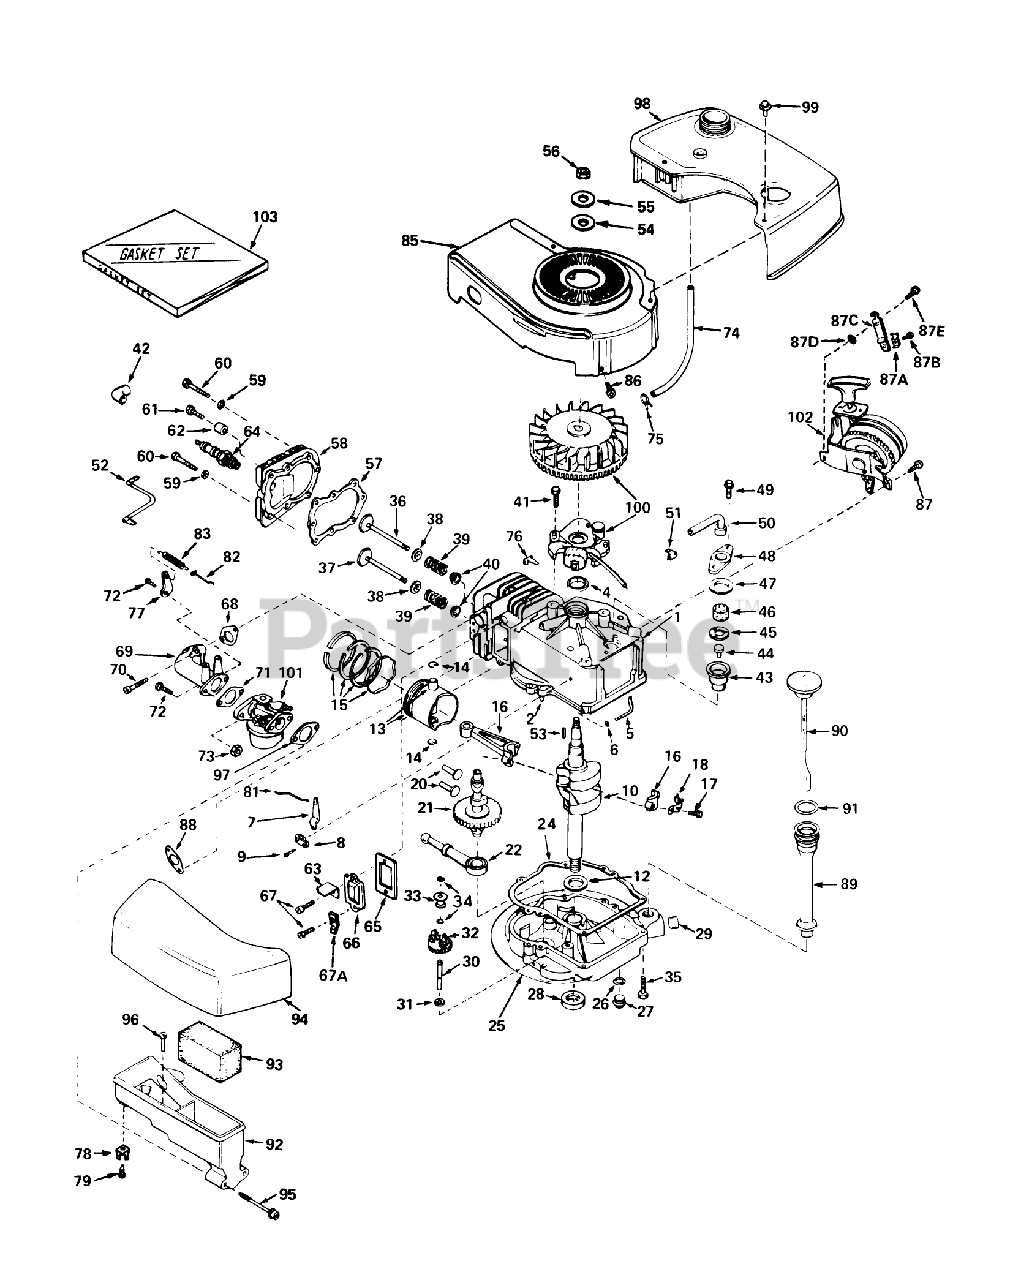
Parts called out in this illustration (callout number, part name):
1	Cylinder Assembly (Incl. Nos. 2, 4 87)
2	Pin-Dowel
4	Seal-Oil
5	Rod, Governor (Incl. No. 36)
6	Washer-Flat
7	Governor Lever
8	Clamp-Lever, Governor
9	Screw
10	Crankshaft
12	Washer-Thrust
13	Piston Pin Assembly (Incl. 2 of No. 14)(Std.)
13	Piston Pin Assembly (Incl. 2 of No. 14)(.010 Oversize)
13	Piston Pin Assembly (Incl. 2 of No. 14)(.020 Oversize)
14	Ring-Retaining, Piston Pin
15	Ring Set-Piston Std.
15	Ring Set-Piston .010 oversize
15	Ring Set-Piston .020 oversize
16	Rod Assembly, Connecting (Incl. Nos. 17 18)
17	Connecting Rod Bolt
18	Plate Lock
20	Lifter-Valve
21	Camshaft(Mech.Comp. Release)
22	Oil Pump ASM
24	Gasket, Mounting
25	Flange Assembly, Mounting (Incl. #27, 28, 29 30)
26	Gasket-Oil Drain
27	Plug Oil Drain
28	Seal-Oil
29	Plug Oil Drain
30	Shaft-Governor
31	Washer-Flat
32	Gear Assembly, Governor
33	Spool, Governor
34	Ring-Retaining
35	Screw (1/4-20 x 1-1/4)
36	Valve, Intake (Incl. Ref. #38, 39 40) (Std.)
36	Valve, Exhaust (1/32" Oversize) (Incl. Nos. 8, 9 10)
37	Valve, Exhaust (Standard) (Incl. Nos. 8, 9 10)
37	Valve, Exhaust (1/32" Oversize) (Incl. Nos. 8, 9 10)
38	Cap-Upper Valve Spring
39	Spring-Valve
40	Cap-Valve, Spring
41	Screw
42	Cover-Spark Plug
43	Body Breather Tube
44	Valve Check
45	2000A37 WIZARD ROTA
46	Element-Breather
47	Gasket-Breather
48	Cover Breather
49	Screw, Hex Hd. w/Conical
50	Tube, Breaker
51	Clip, Breather
52	Wire, Ground
53	Key Flywheel
54	Washer Flat
55	Washer, Belleville
56	Nut, Flywheel
57	Oil Fill Tube
58	Head Cylinder
59	Washer
60	Screw
61	Screw Hex Hd. Cap
62	Space
63	Retainer Clip
64	Plug, Spark (J17LM or equiv.)
65	Gasket-Breather
66	Cover-Valve
67	Screw
67A	Terminal
68	Gasket, Intake
69	Pipe, Intake
70	Screw (1/4-20 x 1)
71	Gasket-Carburetor
73	Nut and Lock Washer (1/4-28)
74	Line-Fuel
75	Clamp-Line, Fuel
76	Clip-Wire
77	Lever-Adjusting, R P M
78	Terminal
79	Screw
81	Link Governor
82	Link Governor Spring
83	Spring Governor
85	Housing, Blower
86	Screw
87	Screw (1/4-20 x 1/2)
87A	Conduit
87B	Screw (10-32 x 3/8)
87C	Bracker
87D	Washer
87E	Screw (1/4-20 X 5/8)
88	Gasket Exhaust
89	Tube, Oil Filler
90	Dipstick, OiI (Incl. No. 91)
91	O-Ring
92	Body Air Cleaner
93	Filer, Air
94	Cove, Air Cleaner
95	Screw Fil Hd.
96	Screw, Hex Hd.
97	Gasket-Air Cleaner
98	Tank Fuel
99	Screw (10-32 x 35/64)
100	LEVER
101	Carburetor
102	Starter
103	53024/VAR.16HP O/P
